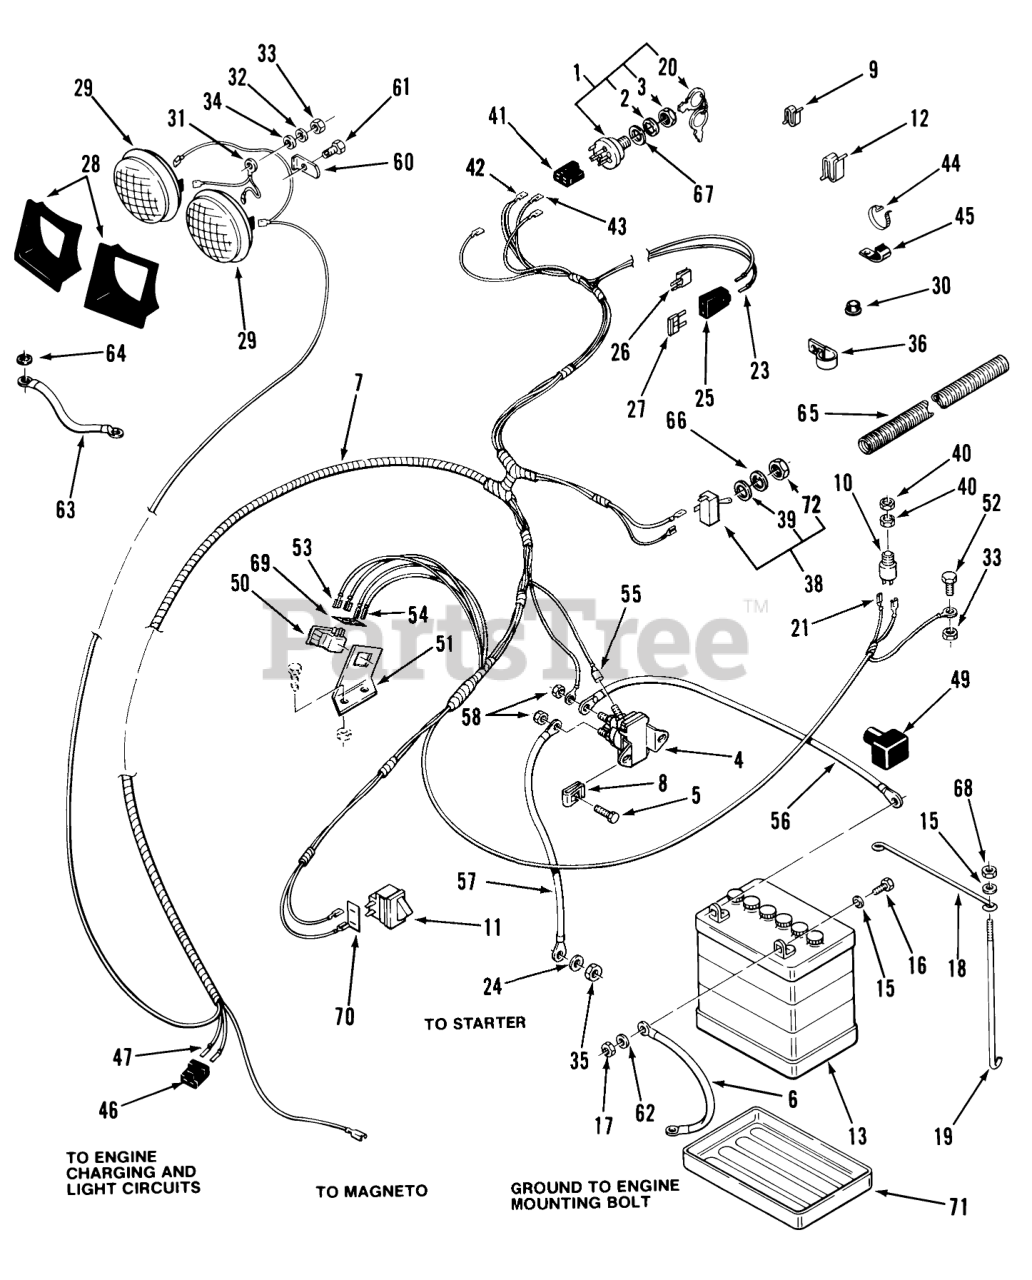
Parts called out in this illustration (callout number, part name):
1	ASSY-SWITCH IGNITION
2	LOCKWASHER
4	Solenoid
5	Screw
6	Wire
7	Wiring Harness Assy 216-5 Only
7	Wiring Harness Assy B-115 Only
7	HARNESS-WIRING
8	Speed Nut
9	SPEED CLIP
10	SWITCH-SEAT
10	SWITCH-BALL
11	SWITCH INTERLOCK
12	CLIP-CABLE
13	Battery
16	Bolt
17	Nut
18	ROD-HOLD DOWN
20	Key-EL
21	Connector
23	TERMINAL-FUSE
24	Washer
25	AUTO-FUSEBLOCK TERM
27	FUSE-BLADE, 15 AMP
28	HEADLIGHT BEZEL ASSY.(SERVICE)
29	HEADLAMP
30	BUSHING-NYLON .75
31	LIGHT GROUND WIRE
32	WASHER 5/16 SAE
33	Nut
34	Washer-Lock
35	Nut
36	CLAMP
38	SWITCH-LIGHTS
39	TAB-WASHER
40	NUT-HEX, SPECIAL
41	CONNECTOR-5 WAY-SERV
42	TERMINAL-TAB RCPT
43	Terminal
44	Cable Tie
44	PLASTIC TIE
45	CLIP
46	Conn Body Part of 7
47	Terminal
49	Boot
50	PTO Interlock Switch
51	BRACKET-SWITCH R
52	Bolt
53	Terminal
54	Wire Terminal (Part of 1)
55	Terminal Part of 5
56	Wire
57	Starter To Solenoid Cable 23.0 in. (58.4 cm) B-115 Only
57	Starter To Solenoid Cable 16.0 in. (40.6 cm) 216-5 Only
58	Nut
60	LOCK-HEADLIGHT
61	Bolt
62	Washer
63	WIRE GROUND
64	Washer-Lock
65	Conduit 216-5 Only
66	Washer
67	Washer
68	Nut
69	SHIELD-DIRT (DPDT)
70	SHIELD-DIRT SPST
71	TRAY BATTERY
72	NUT-HEX
